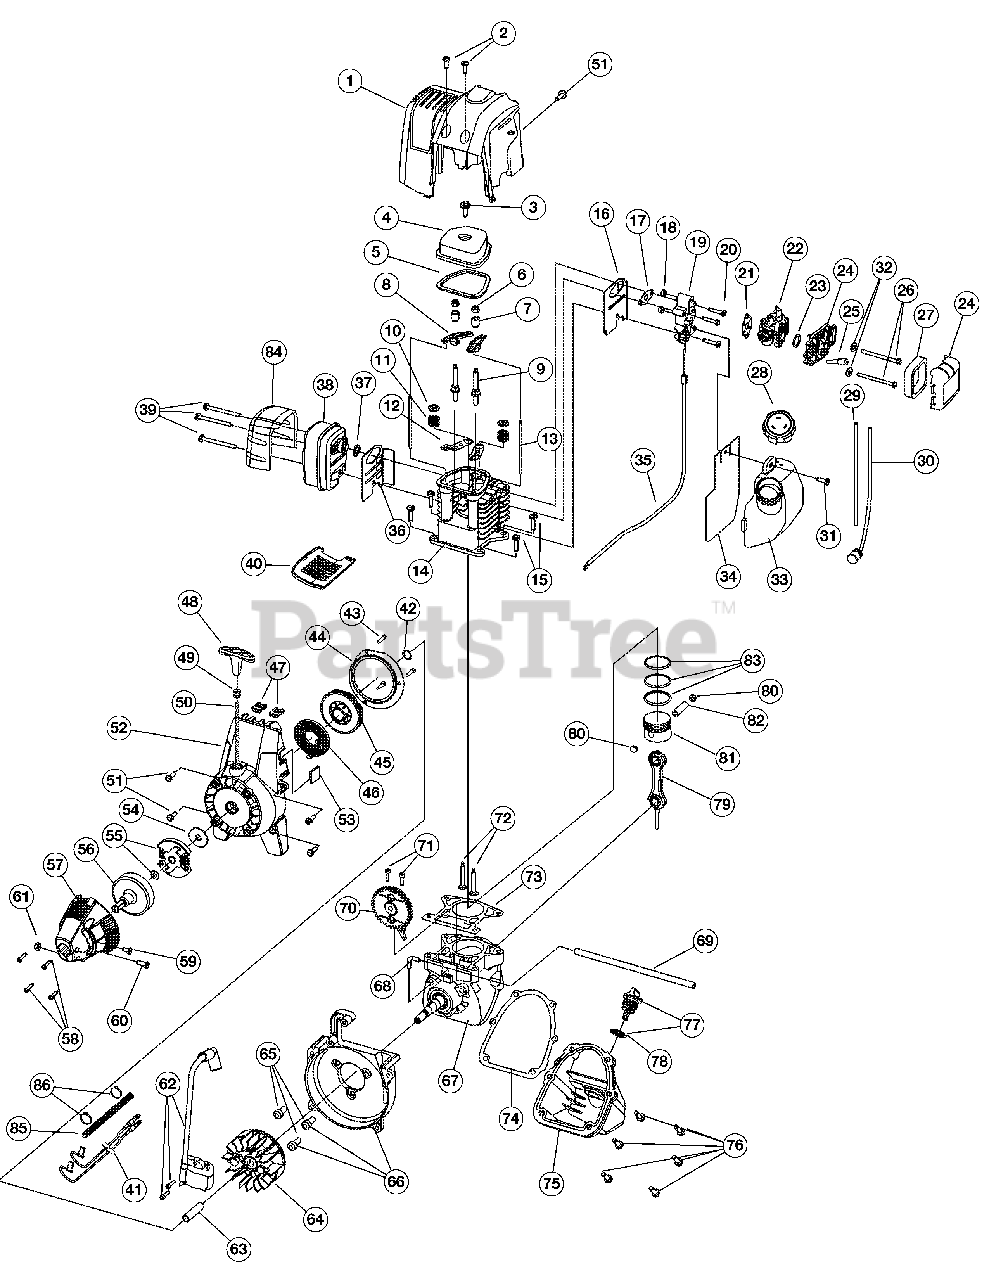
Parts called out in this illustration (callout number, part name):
1	Engine Cover
2	Engine Cover Screws
3	Valve Cover Screw
4	Valve Cover
5	Valve Cover Gasket
6	Rocker Adjustment Nut
7	Rocker Arm Pivot
9	Rocker Arm Stud
10	Valve Spring Retainer
11	Valve Spring
12	Push Rod Guide
13	Push Rod
14	Cylinder Assembly
15	Cylinder Screw
16	Intake Baffle Gasket
17	Carburetor Mount Gasket
18	Nut
19	Carburetor Mount
20	Carburetor Mount Screw
21	Carburetor Gasket
22	Carburetor w/Primer
23	O-Ring, Carburetor
24	Air Filter Cover Assembly
25	Breather Tube
26	Air Filter Mounting Screw
29	Fuel Return Line
30	Fuel Pick-Up Line with Filter
31	Screw
33	Fuel Tank Assembly
34	Fuel Tank Shield
35	Throttle Cable
36	Muffler Baffle
37	Muffler Gasket
38	Muffler
39	Muffler Mounting Screw
40	Muffler Cover
41	Switch Wire Assembly
43	Plate Screw
44	Pressure Plate Assembly
45	Recoil Pulley Assembly
46	Recoil Spring
48	Pull Handle
51	Housing Screw
52	Starter Housing Assembly
53	Wire Grommet
54	Clutch Washer
55	Clutch w/Spacer
56	Clutch Drum
57	Clutch Cover Assembly
58	Cover Screw
59	Anti-Rotation Screw
60	Screw
61	Nut
62	Ignition Module with Screws
63	Spacer
66	Shroud Assembly
67	Crankcase Assembly
69	Breather Hose
70	Cam Bracket Assembly
71	Cam Bracket Screw
72	Valves, Intake and Exhaust
73	Cylinder Gasket
74	Oil Pan Gasket
75	Oil Pan
76	Oil Pan Screw
77	Dipstick Assembly
79	Connecting Rod
80	Wrist Pin Button
81	Piston
83	Piston Ring Set
84	Heat Shield
85	Wire Lead Cover
86	Cable Clamp
